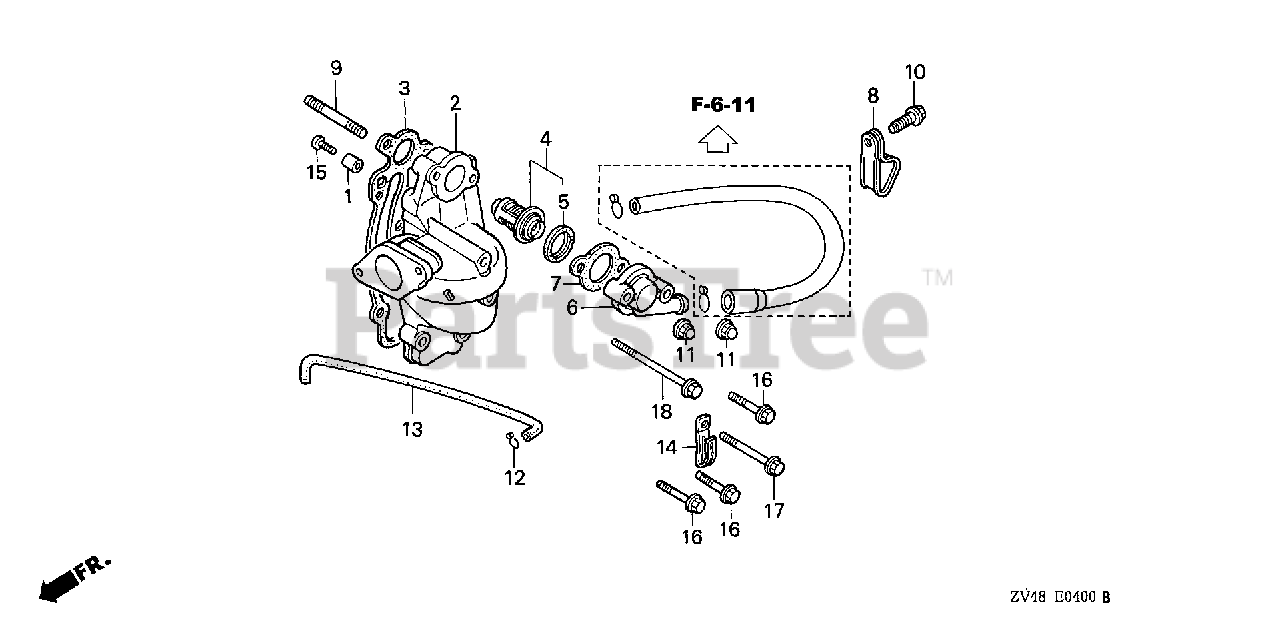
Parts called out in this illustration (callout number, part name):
1	METAL, ANODE
2	MANIFOLD, IN. *NH8* (DARK GRAY)
3	GASKET, IN. MANIFOLD
4	THERMOSTAT ASSY.
5	RUBBER, THERMOSTAT
6	COVER, THERMOSTAT *NH8* (DARK GRAY)
7	GASKET, THERMOSTAT COVER
8	CLAMP, TUBE
9	BOLT, STUD (6X52)
10	BOLT, FLANGE (6X12)
11	NUT, CAP (6MM)
12	CLIP, TUBE (B8)
13	TUBE, WATER CHECK
14	CLIP, TUBE
15	SCREW, PAN (5X20)
16	BOLT, FLANGE (6X30)
17	BOLT, FLANGE (6X60)
18	BOLT, FLANGE (6X75)
